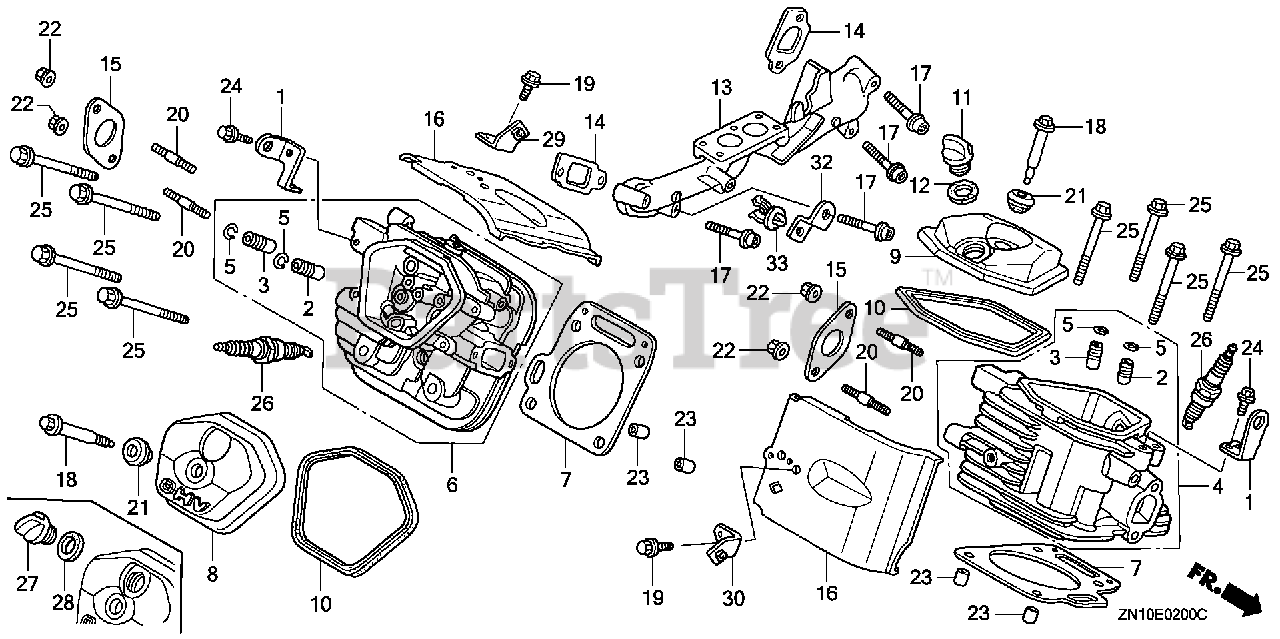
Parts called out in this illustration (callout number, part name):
1	HANGER, ENGINE
2	GUIDE, VALVE (OS)
3	GUIDE, EX. VALVE (OS)
4	CYLINDER HEAD (#1)
5	CLIP, VALVE GUIDE
6	CYLINDER HEAD (#2)
7	GASKET, CYLINDER HEAD
8	COVER, HEAD
9	COVER, HEAD FILLER
10	GASKET, CYLINDER HEAD COVER
11	CAP, OIL FILLER
12	GASKET, OIL FILLER CAP
13	MANIFOLD, IN.
14	GASKET, IN. MANIFOLD
15	GASKET, EX. PIPE Use up to Engine SN 2949254.
15	GASKET, EX. PIPE (WACKER)
16	SHROUD, HEAD
17	BOLT, SOCKET (8X45)
18	BOLT, HEAD COVER
19	BOLT, FLANGE (6X14)
20	BOLT, STUD (8X22)
21	WASHER, HEAD COVER
22	NUT, FLANGE (8MM)
23	PIN A, DOWEL (12X20)
24	BOLT, FLANGE (8X20) Use up to Engine SN 1609606.
25	BOLT, FLANGE (10X81)
26	SPARK PLUG (ZGR5A-4)
29	BRACKET, R. AIR CLEANER
30	BRACKET, L. AIR CLEANER
